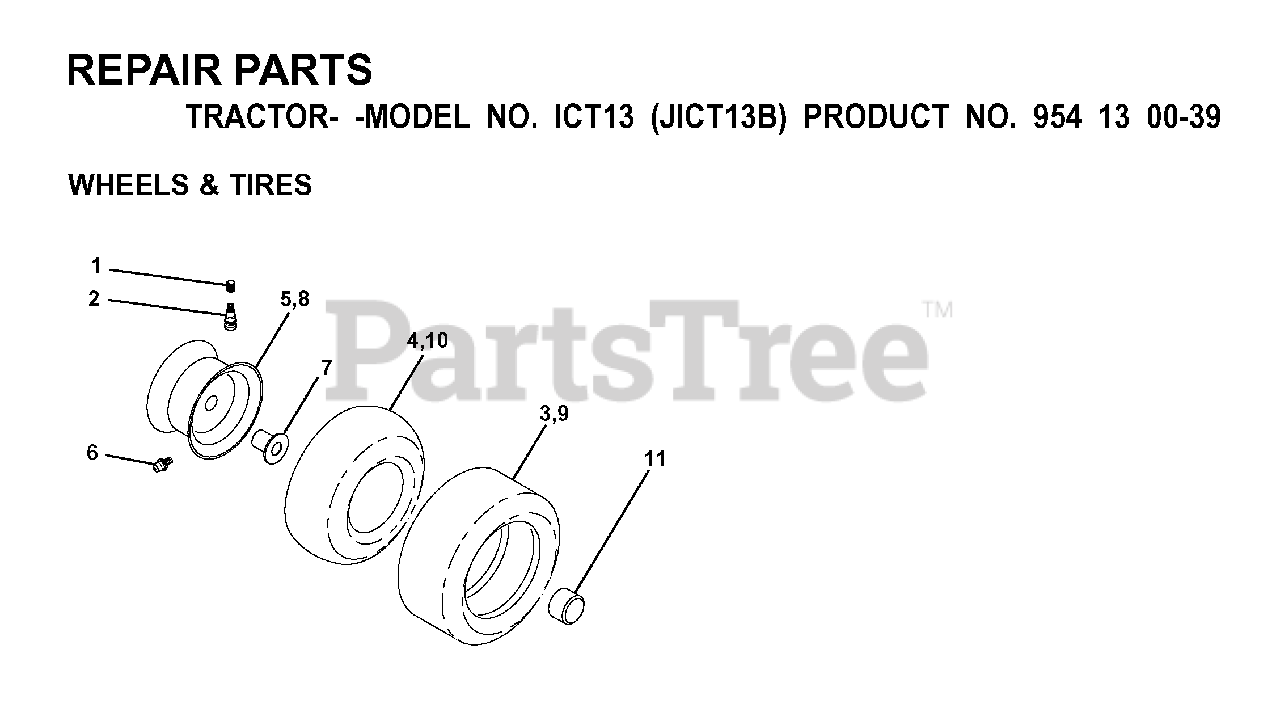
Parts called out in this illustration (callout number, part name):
1	VALVE CAP
2	VALVE STEM LT
3	TIRE HEAVY DUTY
4	TUBE.5.3/4.5/6
5	RIM ASM 6" FRONT SILVER
6	FITTING LT
7	BEARING T
8	RIM ASM 8" REAR SILVER
9	TIRE
10	TUBE
11	CAP-HUB FRONT LT
